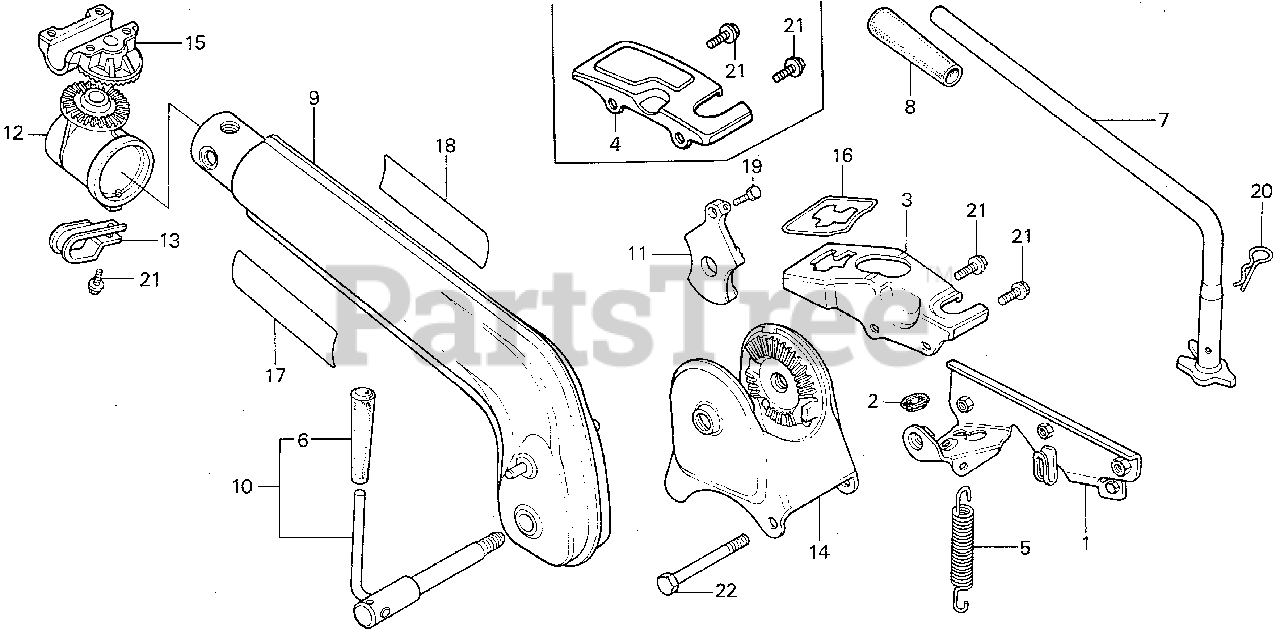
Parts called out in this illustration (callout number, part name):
1	STAY, ENGINE
2	GROMMET, THROTTLE CABLE
3	COVER, CHANGE
5	SPRING, BELT TENSIONER
6	GRIP, LEVER
7	LEVER, CHANGE
8	GRIP, CHANGE LEVER
9	COLUMN, HANDLE *R8* (BRIGHT RED) (NOT AVAILABLE)
10	HANDLE, ADJUSTING
12	BASE, SWING (NOT AVAILABLE)
13	CLIP, CABLE
14	HOLDER, COLUMN
15	FRAME, SWING HANDLE
16	MARK, CHANGE
17	CAUTION, OPERATOR
18	PLATE, EX. GAS CAUTION
19	BOLT, HEX. (6X10)
20	PIN, LOCK (12MM)
21	BOLT, FLANGE (6X12)
22	BOLT, FLANGE (10X95)
